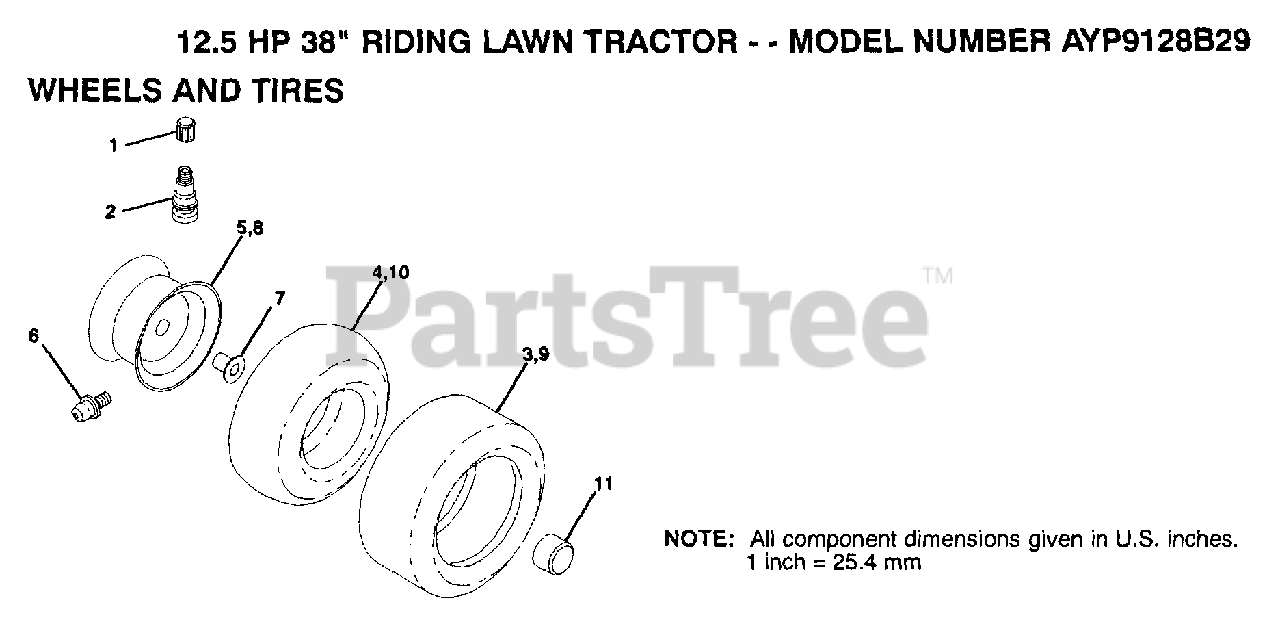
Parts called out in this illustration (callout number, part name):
1	VALVE CAP
2	VALVE STEM LT
4	TUBE.5.3/4.5/6
6	FITTING LT
7	"FLANGE, BEARING"
10	TUBE.18X9.5-8
11	HUB CAP
